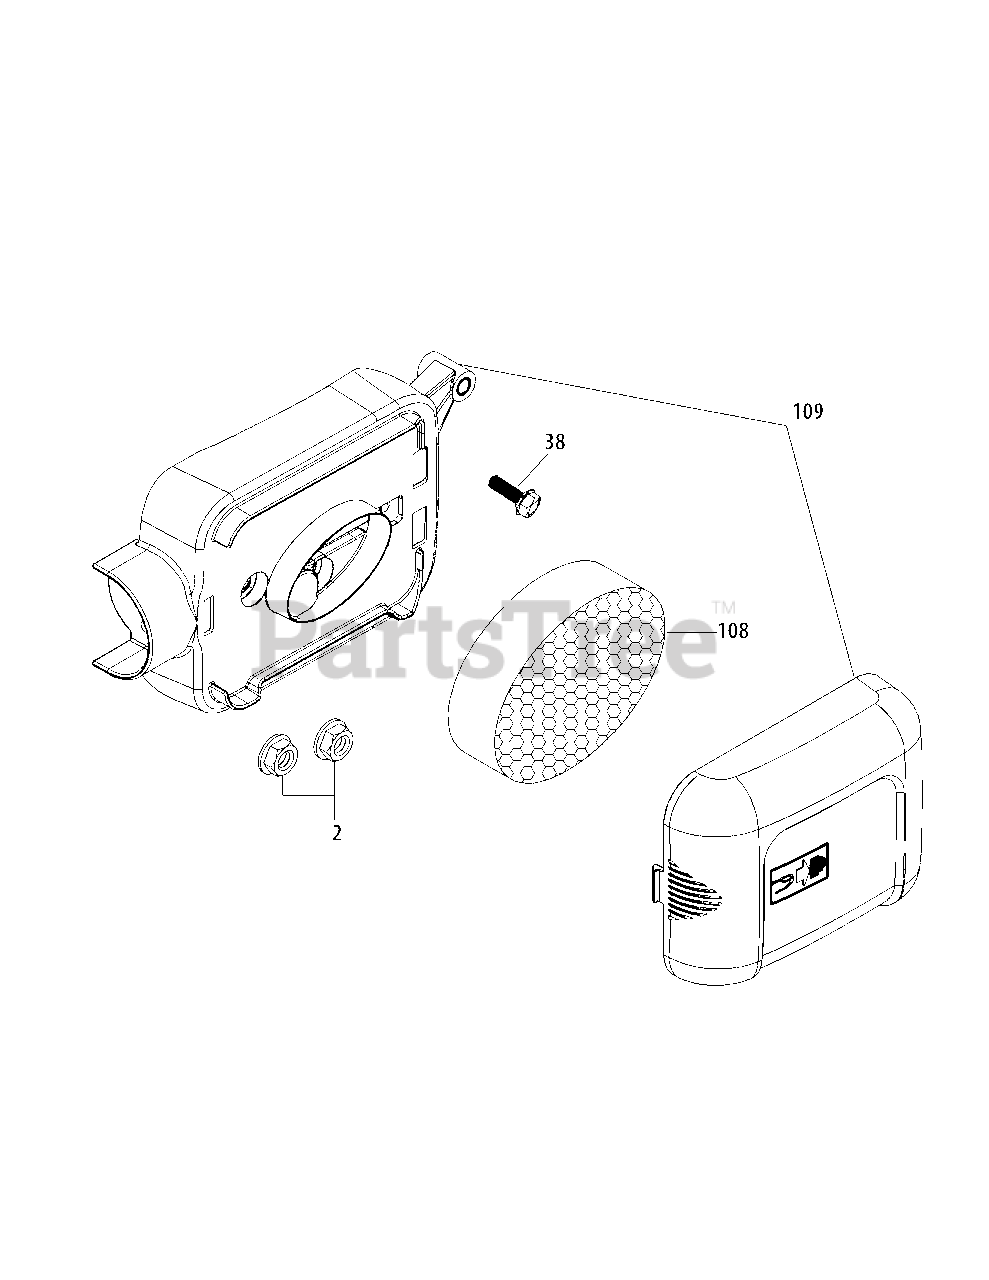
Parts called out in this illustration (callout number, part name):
2	Nut M6X10Mm
38	Bolt M6X30
108	Air Filter Element, Oval
109	Air Filter Base
